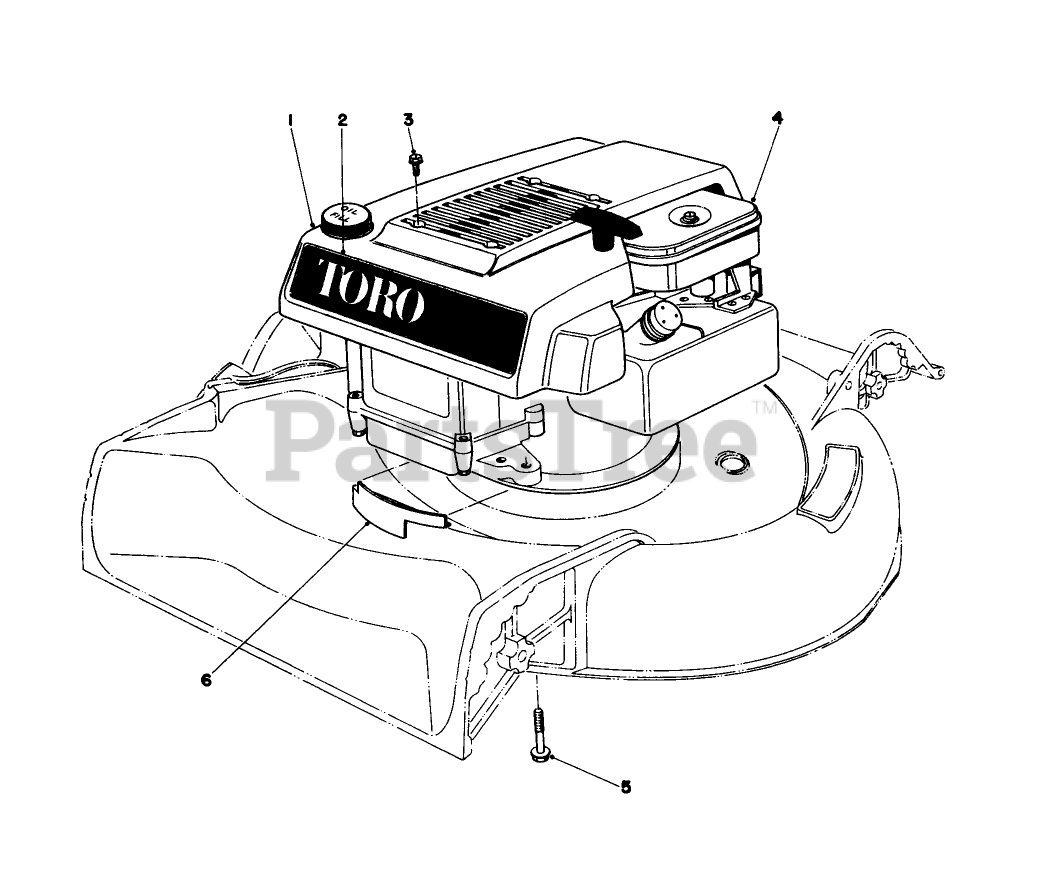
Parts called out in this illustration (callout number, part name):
4	Engine
5	3/8-16 X 2-3/4 CAPSCR
6	HOUSING CAP
